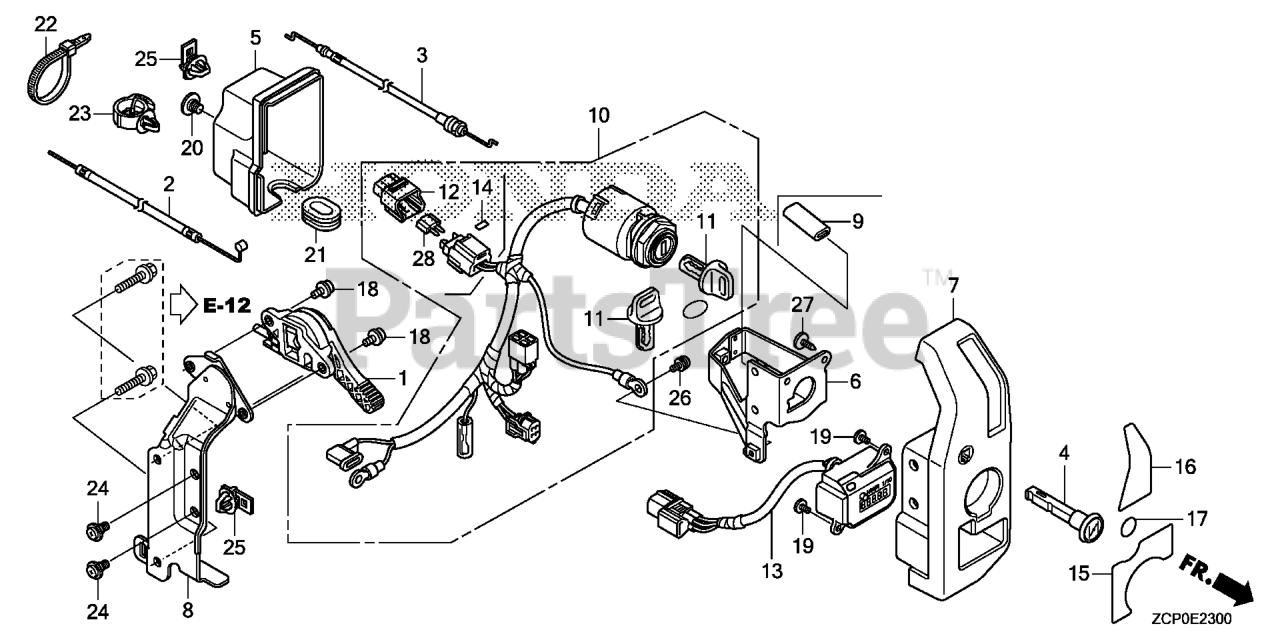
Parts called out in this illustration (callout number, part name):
1	LEVER ASSY., THROTTLE
2	CABLE, THROTTLE
3	CABLE, CHOKE
4	KNOB, CHOKE
5	COVER, CONTROL
6	BRACKET, SWITCH BOX
7	PANEL, CONTROL
8	BRACKET, CONTROL BOX
10	SW ASSY., COMB
11	KEY ASSY., COMBINATION SWITCH (W05)
12	COVER ASSY., FUSE
13	METER ASSY., HOUR
14	LABEL, FUSE (30A)
15	MARK, ENGINE SWITCH
16	MARK, THROTTLE SWITCH
18	BOLT, SOCKET (5X9)
19	SCREW, TAPPING (3X8) (PO)
20	SCREW, SPECIAL (6X8)
21	GROMMET, CONTROL BOX
22	BAND, WIRE (95MM)
23	CLIP, WIRE HARNESS
24	SCREW, PAN (5X10.5)
25	CLIP, CONNECTOR (BLACK)
26	SCREW-WASHER (5X8)
27	SCREW, TAPPING (5X14) (PO)
28	FUSE, MINI (30A)
